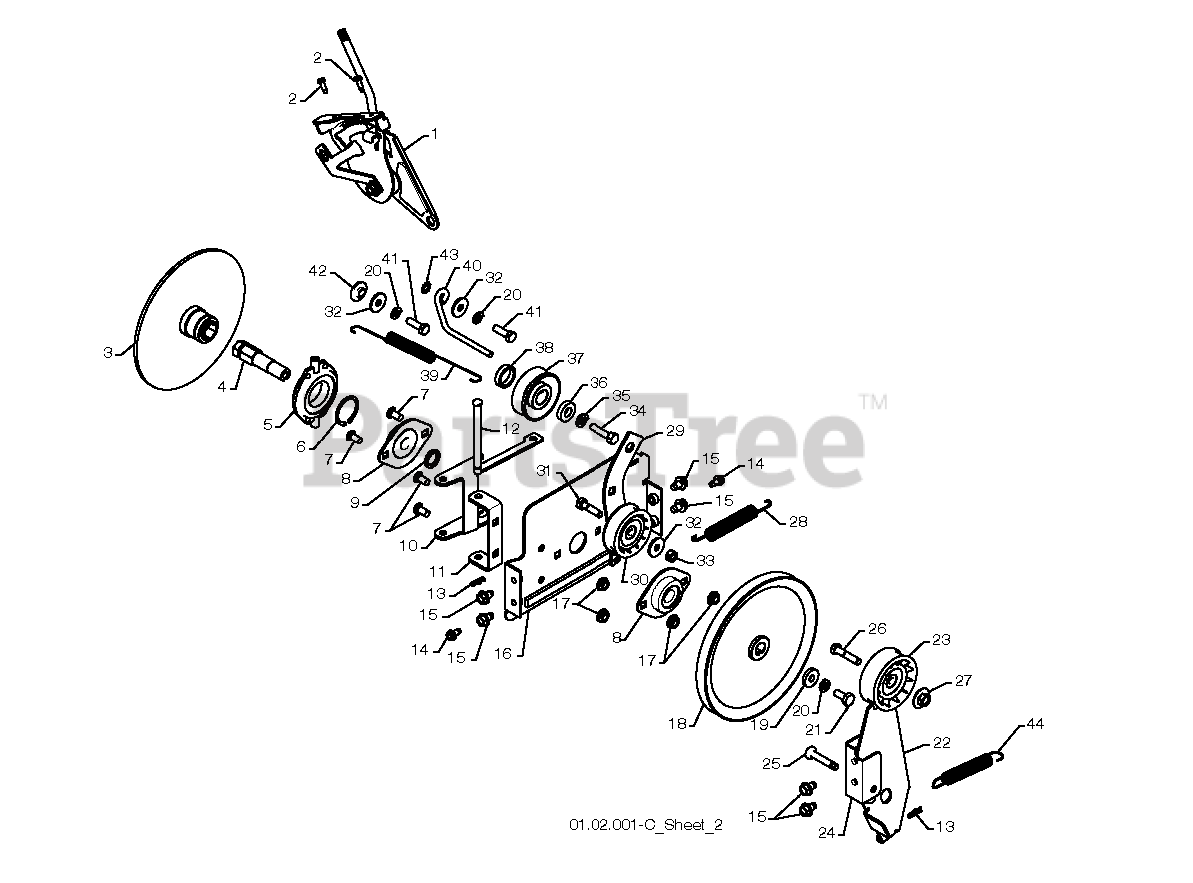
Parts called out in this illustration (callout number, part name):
1	HEAD ASSY SPEED
2	SCREW #10-24 X 5/8
3	DRIVE PLATE WELDMENT
4	SHAFT.HEX.SHORT
5	TRUNNION BEARING ASSY
6	RETAINING RING (2 2)(3 2)
7	BOLT
8	BEARING FLANGE
9	SPACER, BEARING
10	LEVER.SHIFTER.PLATE.BLACK
11	BRACKET, SHIFTER SUPPORT
12	PIN, PIVOT LEVER
13	RETAINER CLIP PM
14	SCREW
15	Screw 5/16-18 x 1/2 Hex, Self Tapping 5/16-18 x 1/2
16	PLATE.DRIVE.MOUNTING.BLACK
17	NUT.FLANGE.5/16
18	PULLEY.TRACTION.7.75
19	WASHER, FLAT
20	WASHER.LOCK.HVY.HLCL.SPR.5/16
21	Screw, Hex Head 5/16-18 x 3/4
22	ARM.IDLER.BRAKE
23	PULLEY.W/SPACER.2.75
24	BRACKET, IDLER PIVOT
25	PIN, IDLER PIVOT
26	HEX BOLT
27	LOCKNUT 5/16-18
28	RP SPRING, TRACTION IDLER
29	ARM, IDLER
30	PULLEY.W/SPACER.2.25
31	BOLT.5/16-18X1-1/4 FULL.THREAD
32	STEEL WASHER
33	NUT.CENTERLOCK.5/16-
34	SCREW, HEX HD 3/8-24 X 1-3/8
35	LOCKWASHER
36	WASHER, FLAT 3/8
37	PULLEY,ENGINE TRACTION DRIVE
38	SPACER.ENGINE.PULLEY
39	SPRING.RETURN
40	BELT.GUIDE.RH
42	RP BUSHING, IDLER PIVOT
43	WASHER EXT TOOTH LOCK 5/16
44	SPRING, BRAKE
